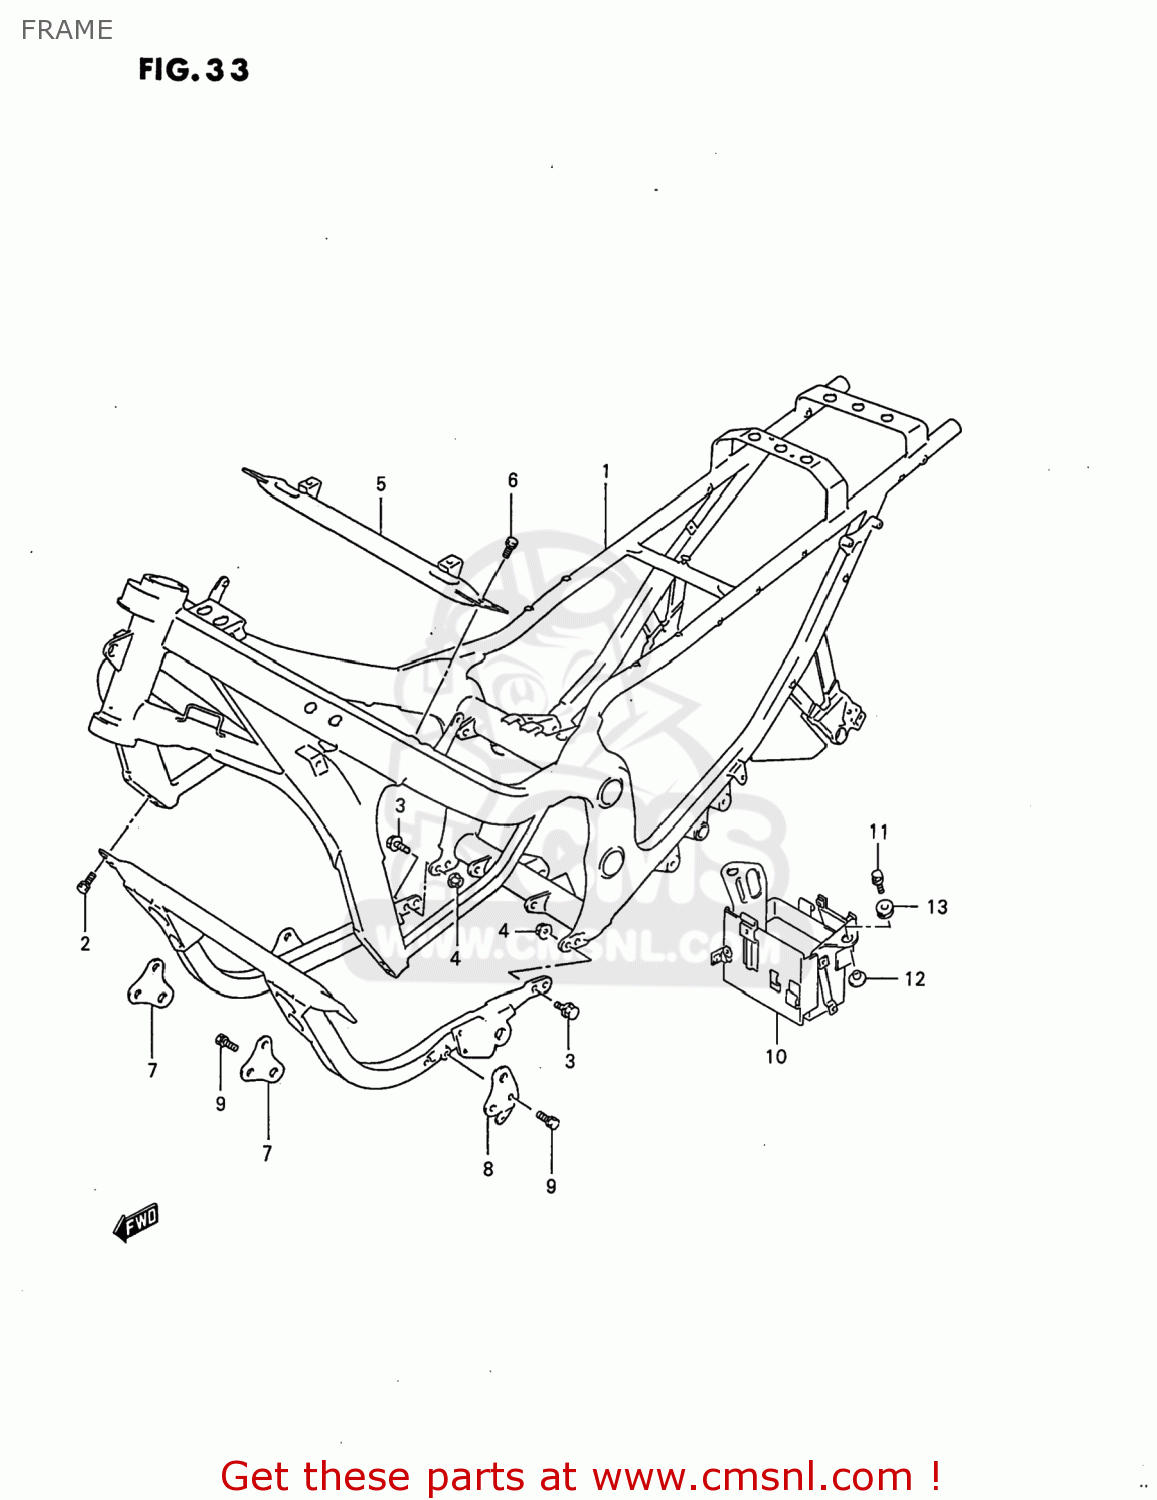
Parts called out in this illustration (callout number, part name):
1	FRAME SET
2	BOLT
3	BOLT
4	NUT
5	TUBE,FRAME BRIDGE NO.2
6	BOLT(8X20)
7	PLATE,ENG MTG NO.1
8	PLATE,ENG MTG NO.2,L
9	BOLT, UPPER
10	HOLDER,BATTERY
11	BOLT
12	WASHER
13	CUSHION
